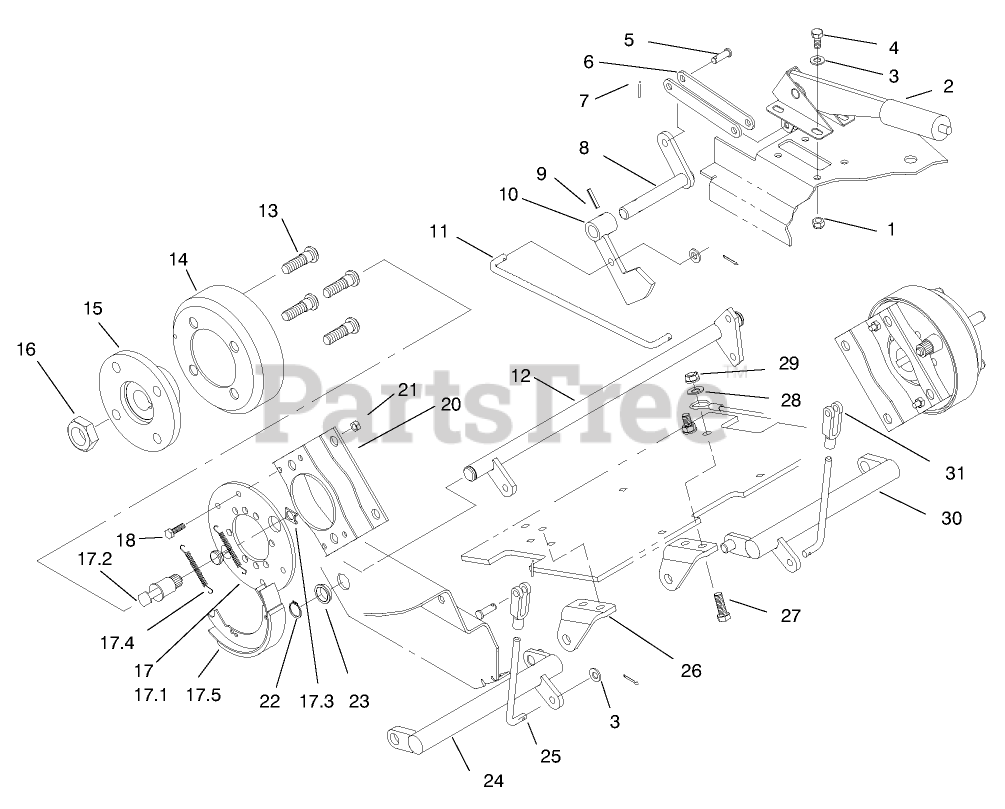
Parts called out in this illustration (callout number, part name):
1	NUT-LOCK, NI
2	LEVER-BRAKE
3	WASHER-PLAIN
4	SCREW-HH
5	PIN-CLEVIS
6	LINK-BRAKE
7	PIN-COTTER
8	TRANSFER SHAFT ASM
9	PIN-SPIRAL
10	BRAKE HUB ASM
11	LINK - CONNECT
12	TORSION SHAFT ASM
13	STUD-DRIVE
14	DRUM-BRAKE
15	Hub-Wheel
16	NUT-LOCK
17	BrakeASM
17.1	PLATE-BACKING
17.2	Cam Shaft
17.4	SPRING-RETURN
17.5	SHOE-BRAKE
18	SCREW-HH
20	Bracket-Brake
21	NUT-LOCK, NI
22	Ring-Snap
23	BUSHING
24	RH BRAKE LEVER ASM
25	ROD-BRAKE
26	MOUNT-LEVER, BRAKE, RH
27	SCREW-HH
28	WASHER-FLAT
29	NUT-LOCK, NI
30	LH BRAKE LEVER ASM
31	YOKE
32	NUT-JAM
33	NUT-JAM
34	CLEVIS-ADJUSTABLE
